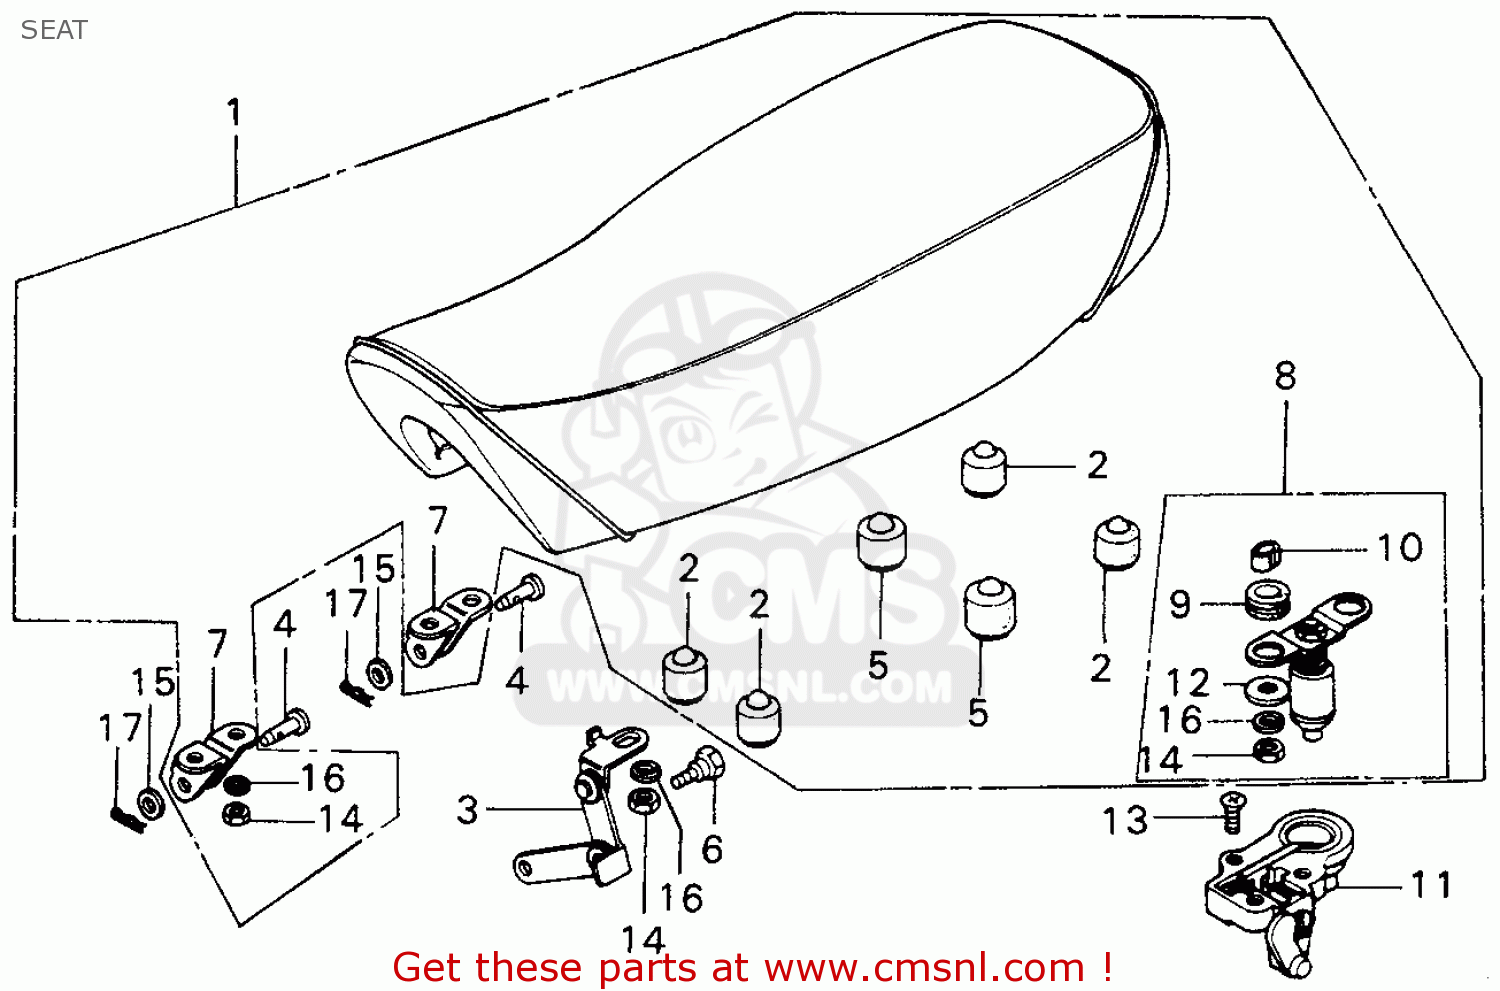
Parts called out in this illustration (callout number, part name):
1	SEAT ASSY.
2	DAMPER SEAT
3	HINGE ASSY., SEAT
4	PIN,SEAT HINGE
5	RUBBER,SEAT SETT.
6	BOLT, SEAT SET HINGE
7	HINGE, SEAT
8	BAR,SEAT LOCK
9	CUSHION RUBBER LO
10	COLLAR,SEAT LOCK
11	SEAT LOCK ASSY.
12	LOCK,WASHER TANK
13	SCREW,FLAT,6X12
14	NUT HEX 6MM
15	WASHER PLAIN 6MM
16	WASHER,SPRING,6MM
17	PIN,LOCK 6MM
